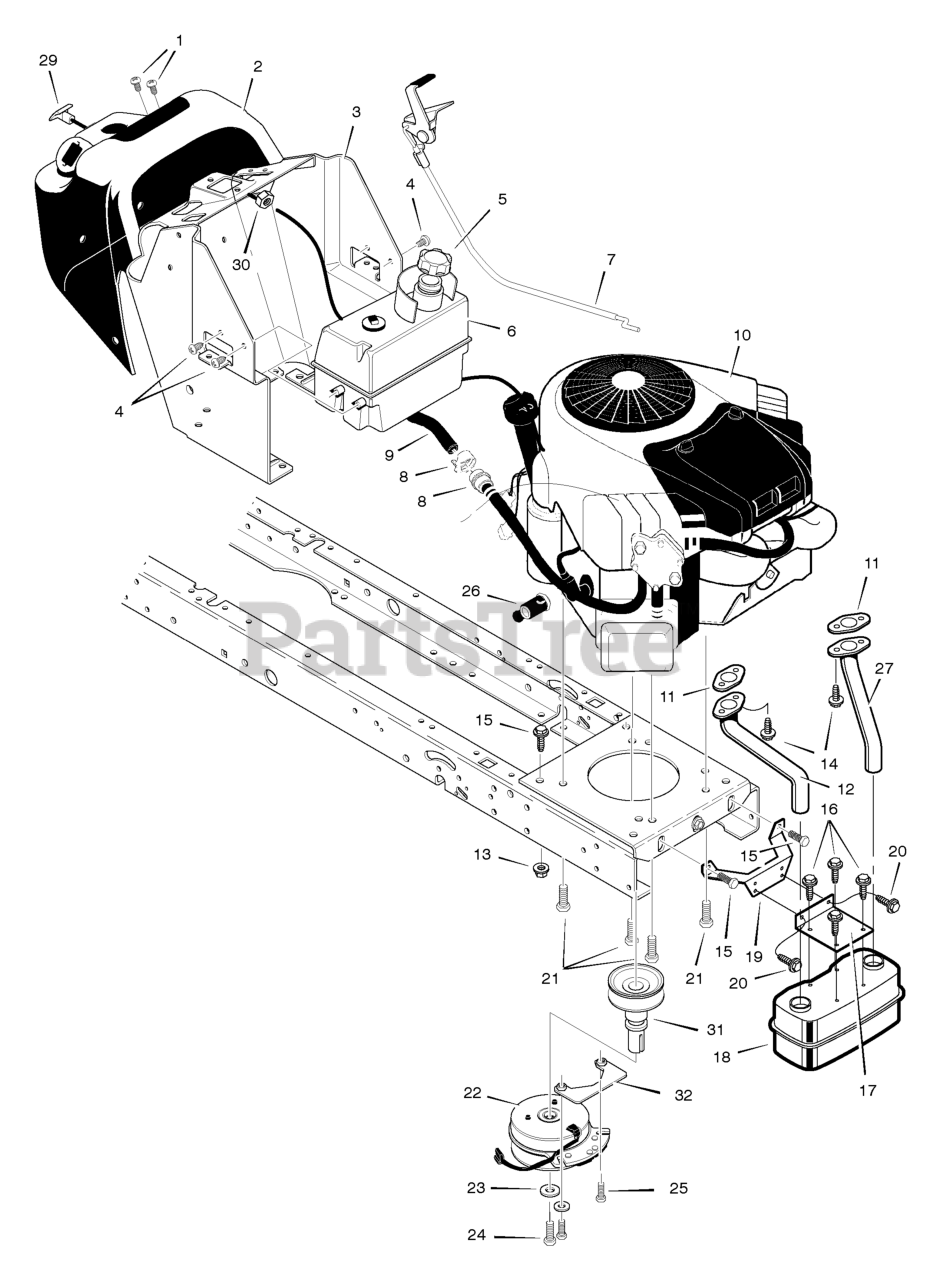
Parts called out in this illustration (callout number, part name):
1	Screw
3	Console
5	Cap, Fuel
6	Tank, Fuel
7	Control, Throttle
8	Clamp, Hose
9	Fuel Line (Must cut to length)
10	Engine *
11	Gasket, Exhaust
12	Tube, Right Exhaust
13	Nut
17	Bracket, Muffler
18	Muffler
19	Bracket, Muffler Mount
21	Bolt, Engine Mount
22	Clutch, Electric
23	Washer
26	Drain, Oil
27	Tube, Left Exhaust
30	Nut
31	Adapter, Pulley
32	Plate, Brake
